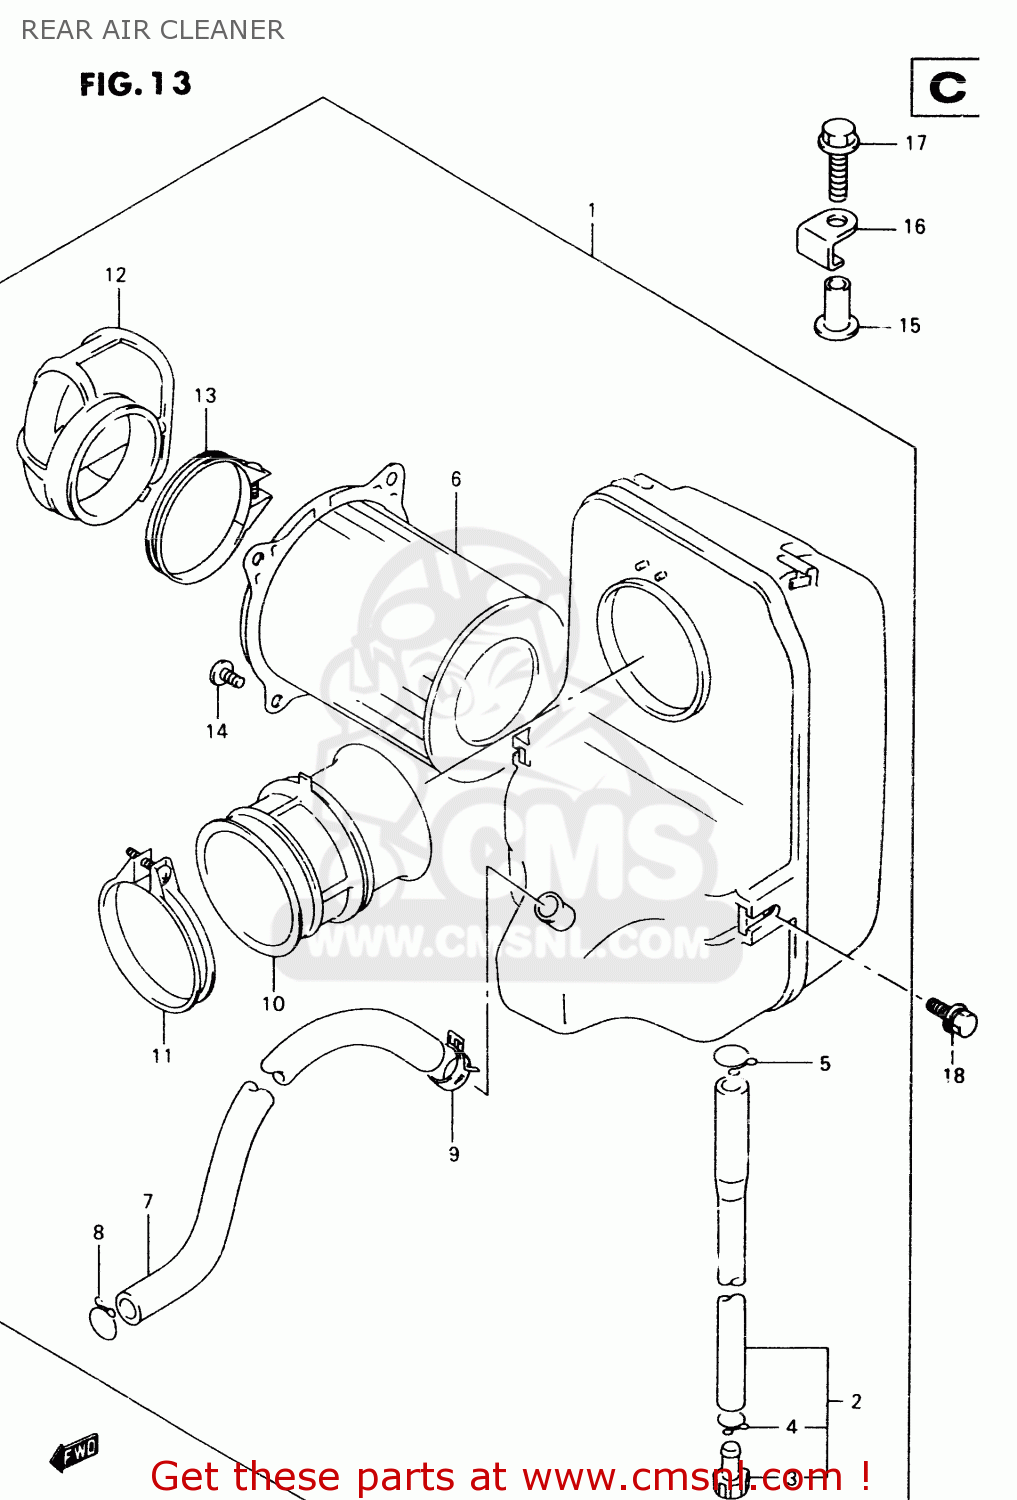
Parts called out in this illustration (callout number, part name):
1	CLEANER ASSY,AIR RR
2	TUBE,DRAIN
3	STOPPER,DRAIN
4	CLIP
5	CLIP
6	FILTER ASSY
7	TUBE,BREATHER
8	CLIP
9	CLIP
10	TUBE,OUTLET
11	CLAMP
12	TUBE,INLET
13	CLAMP
14	SCREW
15	SPACER,AIR CLEANER RR
16	PLATE,AIR CLEANER RR
17	BOLT
18	BOLT
